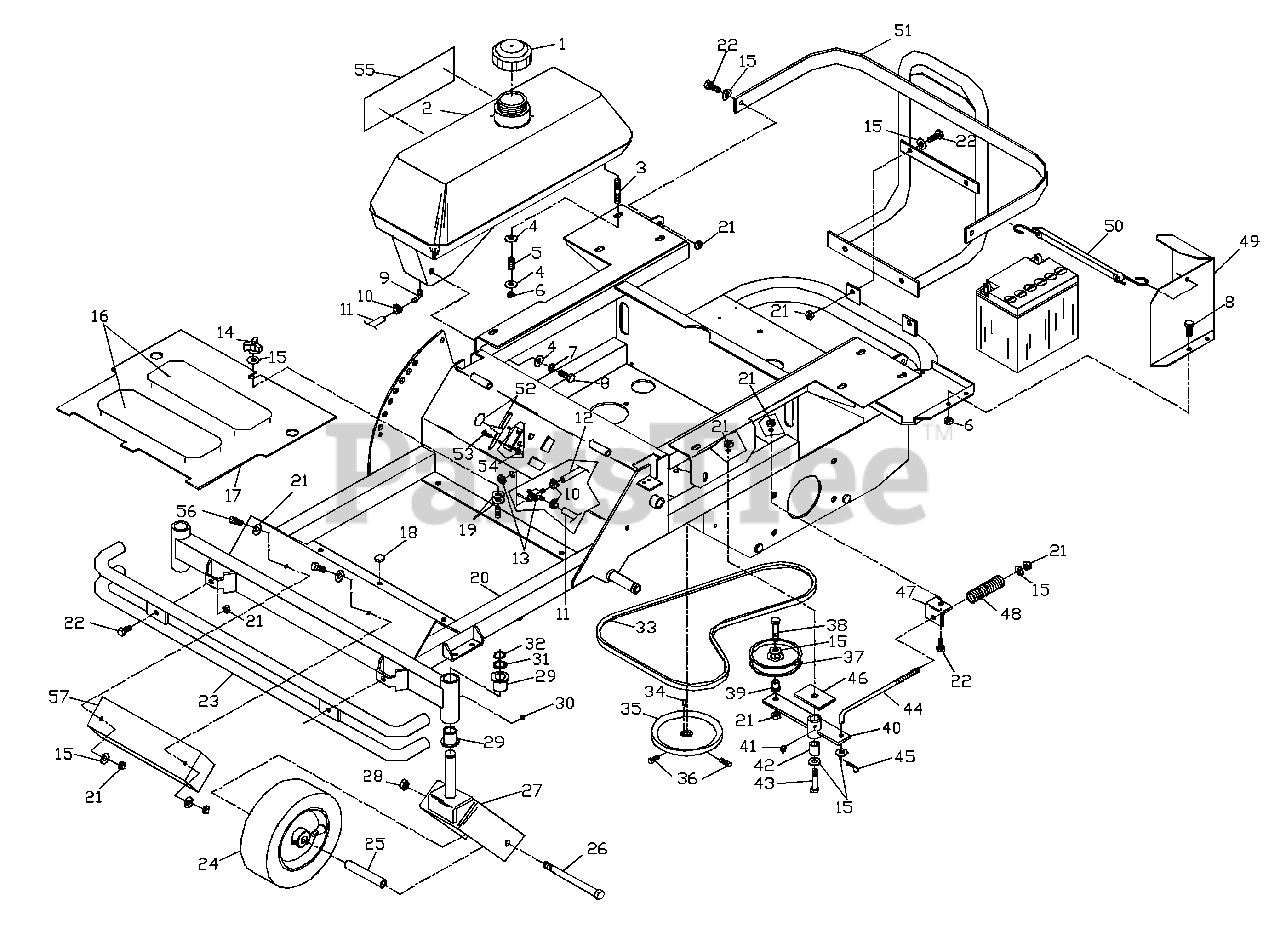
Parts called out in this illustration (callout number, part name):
3	5/16C STUD
4	5/16 FLAT WASHER
6	NUT 5/16C CENTERLOCK
7	5/16 LOCKWASHER
8	HCS 5/16C X 3/4
9	90 DEG. HOSE BARB
10	HOSE CLAMP
11	FUEL LINE, TANK
12	FUEL LINE, ENGINE
13	FUEL VALVE
15	3/8 FLAT WASHER
16	ANTI-SKID PAD
17	FOOTPLATE
18	BUMPER, RUBBER
19	3/8 DISC WASHER
20	FRAME W/DECALS
21	NUT 3/8C CENTERLOCK
22	HCS 3/8C X 1
23	BUMPER, FRONT
24	CASTER TIRE (COMPLETE)
24	ROLLER BEARING 1"
24	ZERK
24	FLANGED BEARING
24	ROLLER BEARING 2 1/4"
26	HCS 1/2C X 5 1/2
27	YOKE WELDMENT
28	NUT 1/2C NYLOC
29	FLANGE BUSHING
31	MACHINERY BUSHING
32	7/8" RETAINING RING
34	KEY 5 MM SQ. X 25 MM
36	5/16C X 5/8 SQ. HEAD
37	IDLER PULLEY
38	HCS 3/8C X 1 3/4
39	IDLER FLANGE BUSHING
40	IDLER ARM WELDMENT
41	45 DEG. ZERK
42	PIVOT BUSHING
43	HCS 3/8C X 3
44	TENSION ROD
45	#2 HAIRPIN
46	SUPPORT PLATE
47	TENSION BRACKET
48	COMPRESSION SPRING
49	BATTERY GUARD W/DECALS
50	BATTERY STRAP
51	ENGINE GUARD W/DECALS
52	THROTTLE CABLE
53	#10-24 X 1/2 HCS
54	#10-24 NYLOC NUT
55	DECAL, ZTH 4817
55	DECAL, ZTH 4819
56	HCS 3/8C X 2 1/4 GD5 (19 HP ONLY)
57	WEIGHT BLOCK (19 HP ONLY)
